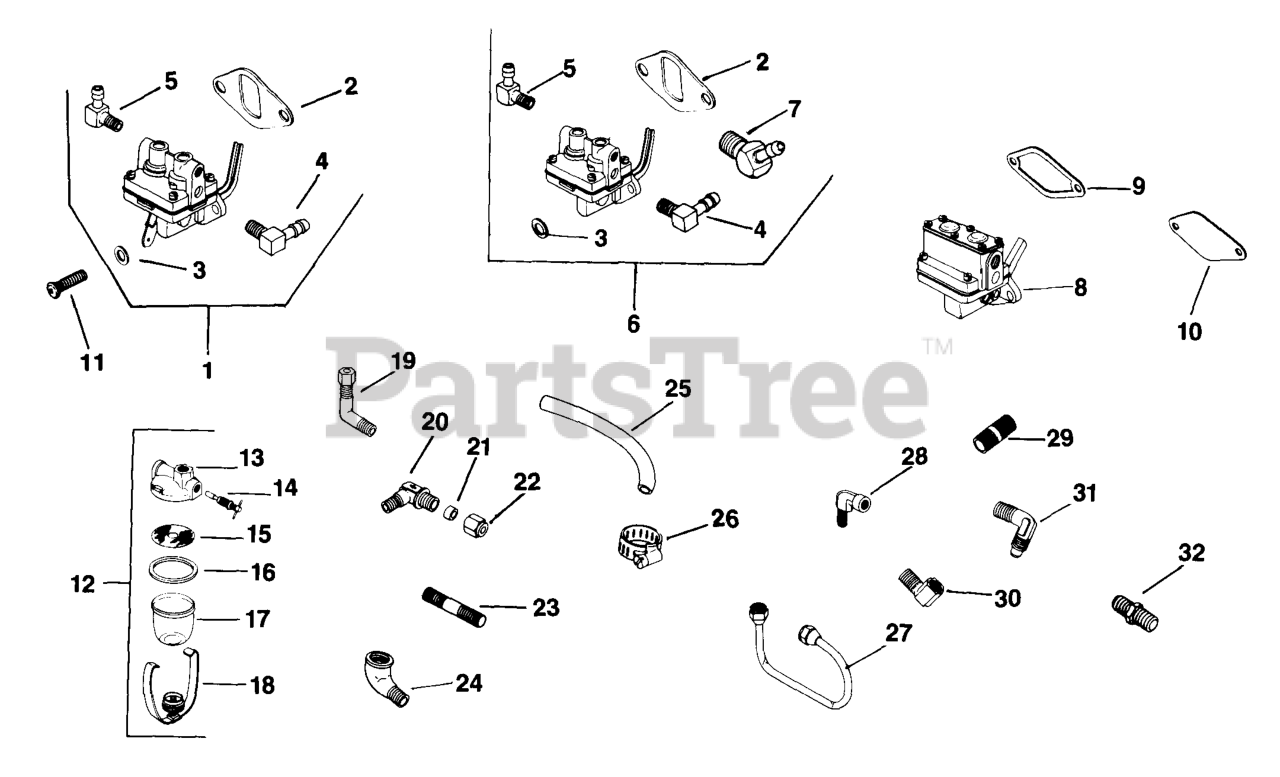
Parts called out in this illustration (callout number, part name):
2	GASKET - USE 25 041 09
10	PLATE, FUEL PUMP COVER
11	SCREW, SEMS 1/4-20X3/4"
